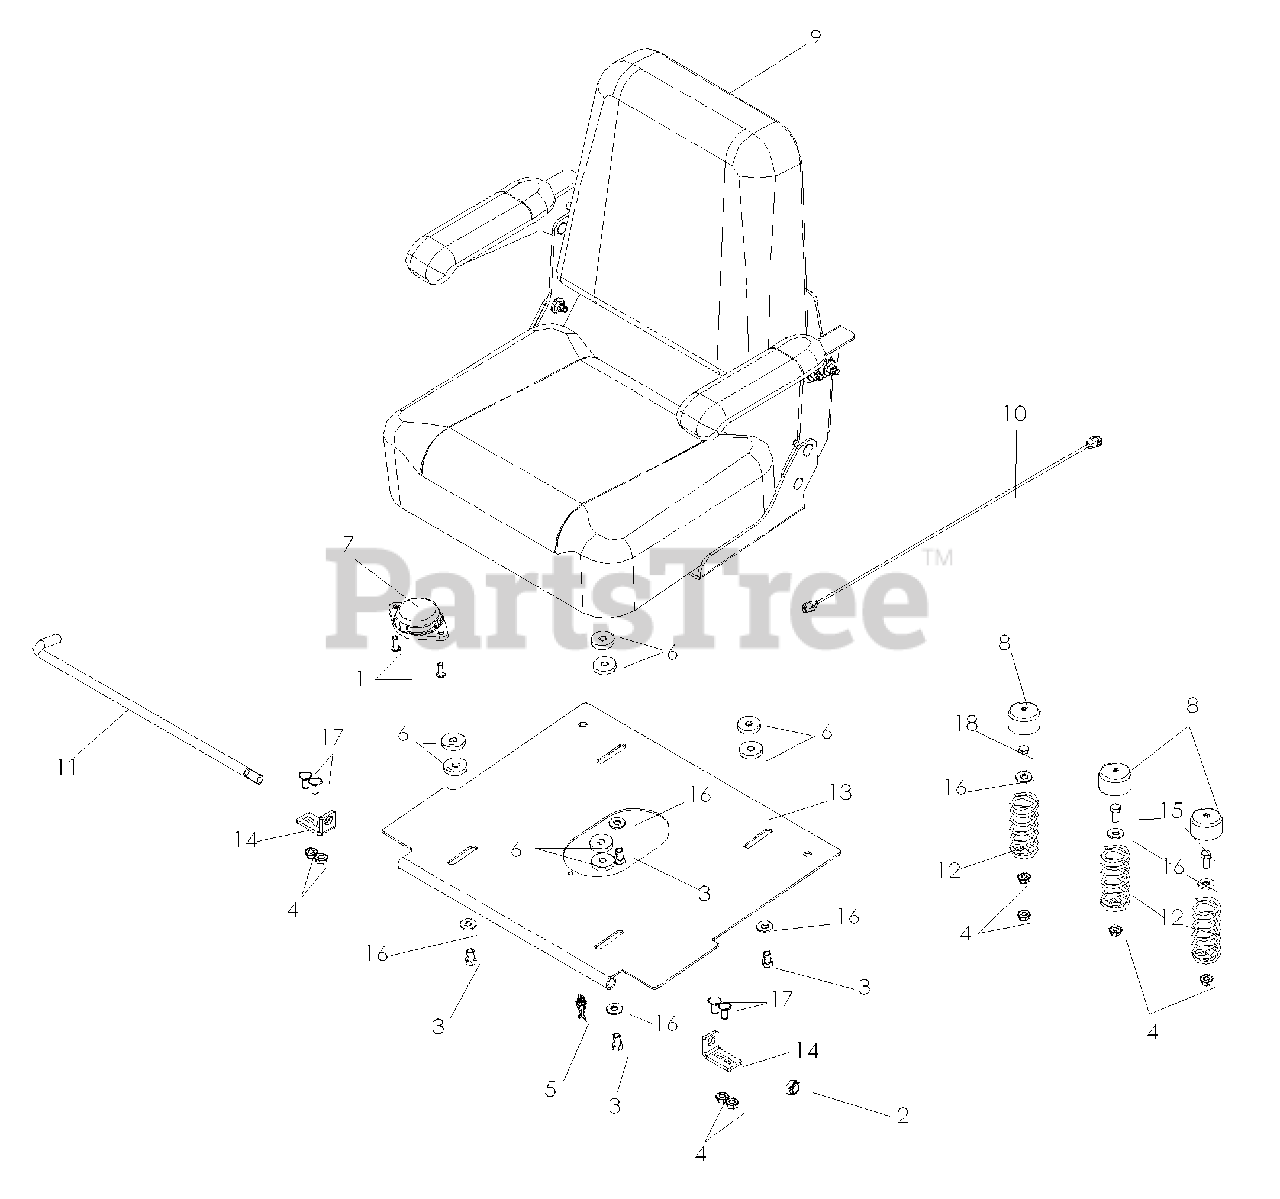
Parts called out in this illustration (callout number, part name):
1	SCR 1/4-20X3/4 SLTD RDHD GR2ZD
2	NUT 1/2-13 HEX JM NYL
3	CAPSCREW 5/16 X 1/1/2 HEX HEAD
4	5/16-18 FLANGED L-NUT
5	LINK RETAINER
6	WASHER NYLON
7	SEAT SWITCH MILSCO
8	SPRING CAP
9	SEAT CORDURA
10	SEAT LANYARD
11	SEAT PIN
12	SEAT SPRING
13	SEAT PLATE DK-BLUE
14	SEAT PIVOT DK-BLUE
15	HCS 5/16C X 3/4
16	FLAT WASHER 5/16 SAE
17	BOLT 5/16C X 3/4" CARRIAGE
18	HCS 5/16C X 1 1/4
